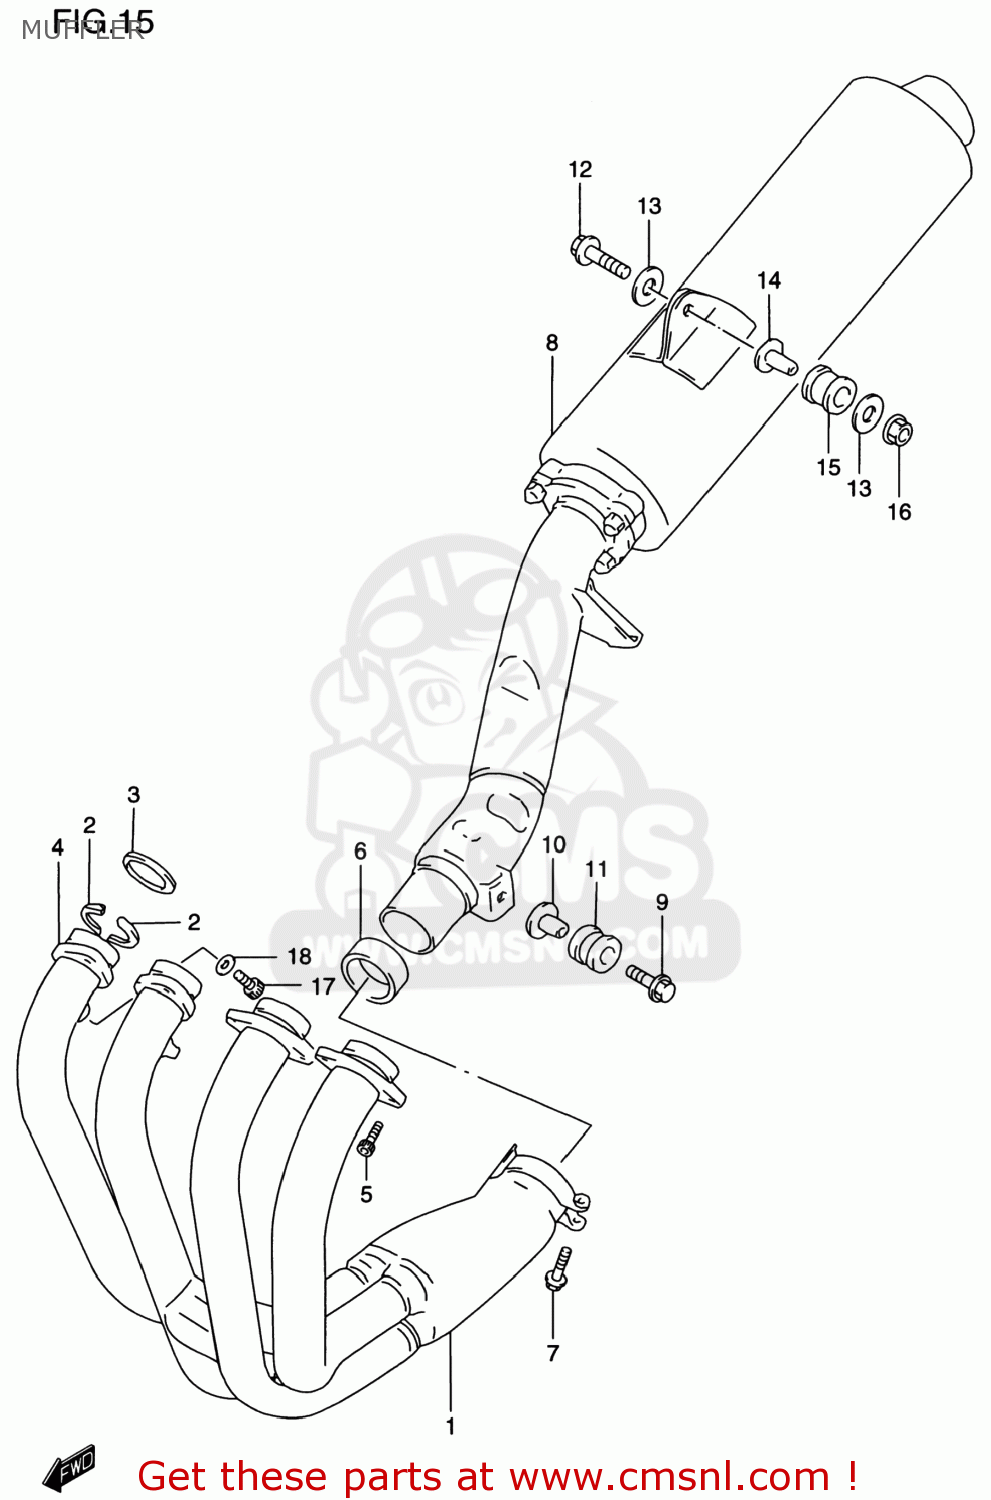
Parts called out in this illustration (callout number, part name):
1	EXHAUST
2	PLATE,EXHAUST PIPE
3	GASKET,EXHAUST (NAS)
4	CLAMP,EXHAUST PIPE
5	BOLT
6	CONNECTOR,MUFFLER
7	BOLT
8	BODY,MUFFLER
9	BOLT 8X40
10	SPACER(8.6X12X24.2)
11	CUSHION
12	BOLT
13	WASHER (8.1X33X1.6)
14	SPACER(8.6X12X27.1)
15	CUSHION
16	NUT
17	BOLT(6X10)
18	WASHER(7X12X1)
